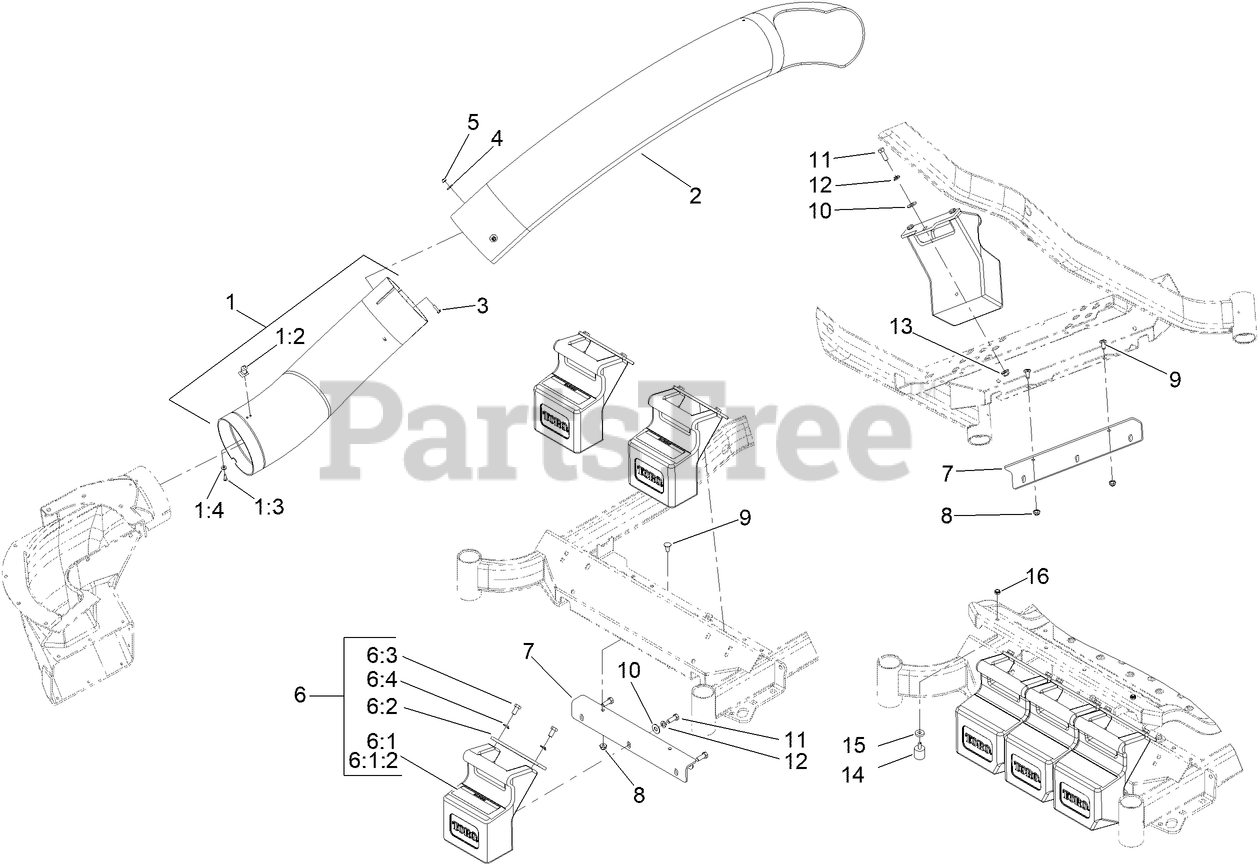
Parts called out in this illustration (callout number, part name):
1	LOWER TUBE ASM
1:2	LATCH-KEEPER
1:3	SCREW-PPH
1:4	WASHER-FLAT
2	TUBE-UPPER
3	SCREW-HWH
4	WASHER-FLAT
5	NUT-LOCK, NI
6	WEIGHT ASM
6:1	WEIGHT W/DECAL ASM
6:1:2	DECAL-WARNING, COUNTERWEIGHT
6:2	TAB-SUPPORT, WEIGHT
6:3	SCREW-HH
6:4	WASHER-LOCK
7	BRACKET-MOUNT, WEIGHT
8	NUT-HF, NI
9	SCREW-CARR
10	WASHER-FLAT
11	SCREW-HH
12	WASHER-LOCK
13	NUT-HF, NI
14	BUMPER-RUBBER
15	SPACER
16	NUT-LOCK, NI
